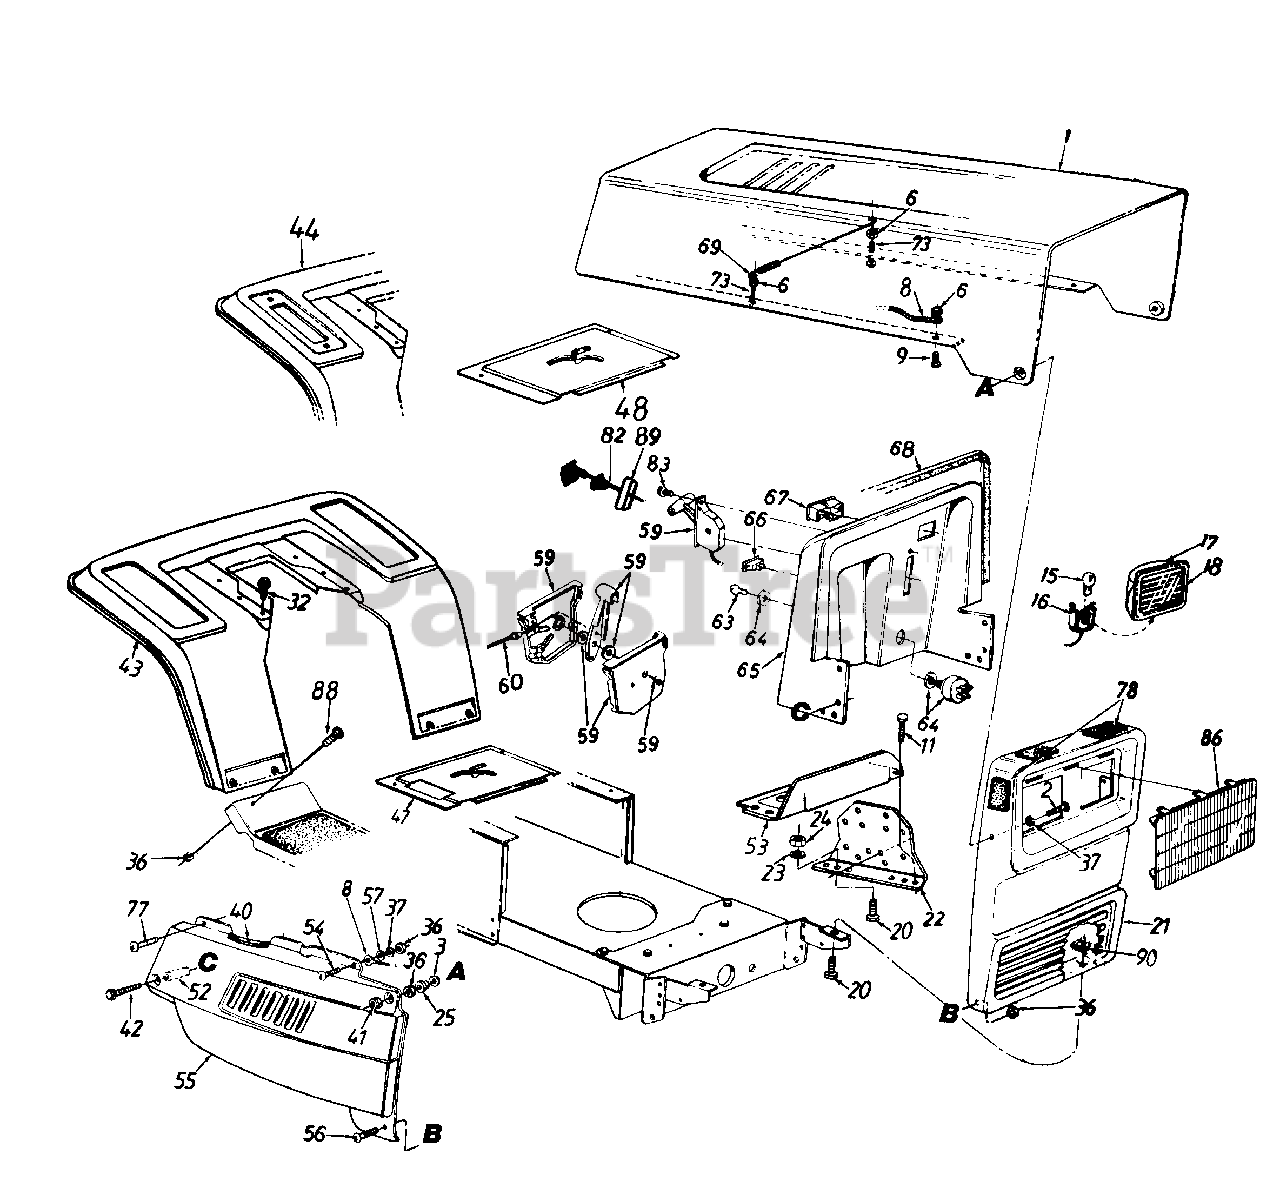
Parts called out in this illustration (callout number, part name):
3	Washer .39" I.D. x .62"
6	Hex Sems Nut #10-24 Thd.
8	Hood Stop
9	Truss Hd. Scr. #10-24 x 1/2"
11	Hex Wash. Hd. B-Tap Scr. 5/16-18 x .5" Lg.
15	Bulb
16	Twist Lock - Bulb Socket
17	Headlight Housing
18	Lens
20	Hex Bolt 5/16-18 x .75" Lg.
24	Hex Nut 5/16-18 Thd.
25	Shld. Spacer
36	Hex Sems Nut 1/4-20 Thd.
40	Trim Strip - 12"
41	Acorn Nut 1/4-20 Thd.
42	Hex TT-Tap Scr. 1/4-20 x 1.75" Lg.
52	Spacer 1.32" Lg.
57	Fl-Wash 281" I.D. x .73" O.D.
59	Throttle Control Box Ass'y.
60	Throttle Control Wire
63	Ignition Key
64	Ignition Switch
67	Ammeter
68	Trim Strip - 31"
69	Hood Spring
73	Hex Scr #10-24 x 1.0" Lg
77	Hex Wash Hd Tap Scr 1/4 x .75" Lg.
78	Foam Strip 3/8 x 1-1/8" x 1-1/2 Lg.
82	Choke Control 29" Lg.
83	Truss Mach AB-Tap Scr #10 x 5" Lg.
86	Headlight Bezel
88	Truss Mach. Scr 1/4-20 x 5" Lg.
89	Retainer Clip
90	U-Nut 5/16-18 Thd.
